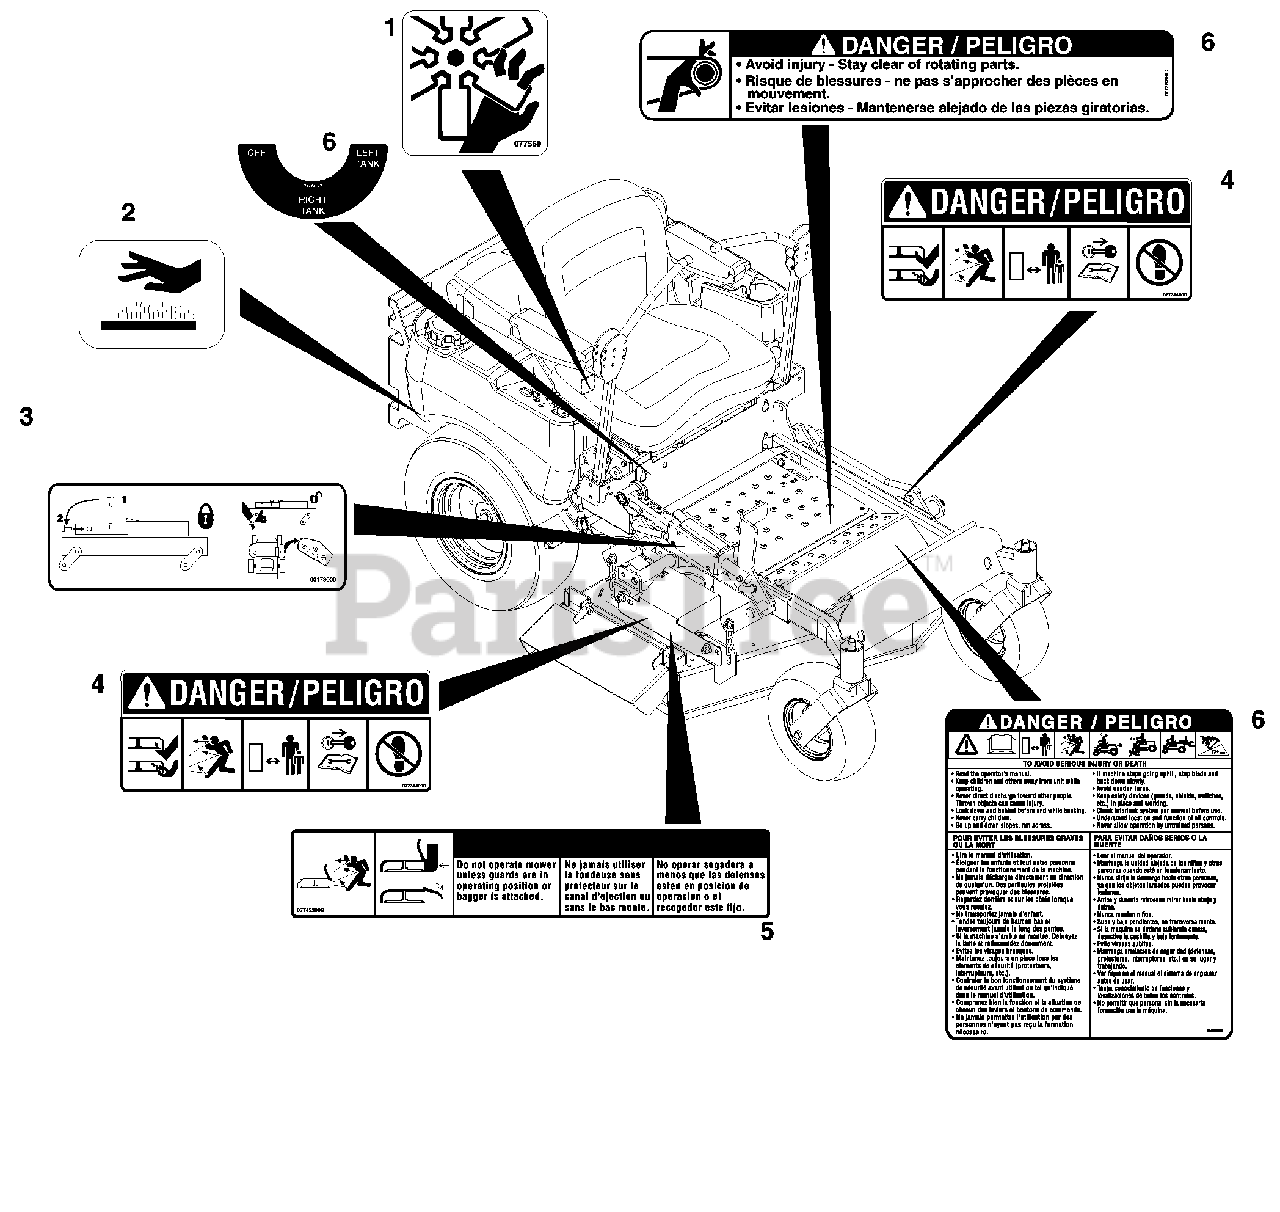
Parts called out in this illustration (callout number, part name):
1	Decal, Danger Fan
2	Decal, Hot Surface
3	Decal, Deck Service
4	Decal, Mower Pan Head Danger
5	Decal, Warning
6	Set, Decal Common Danger/Fuel
